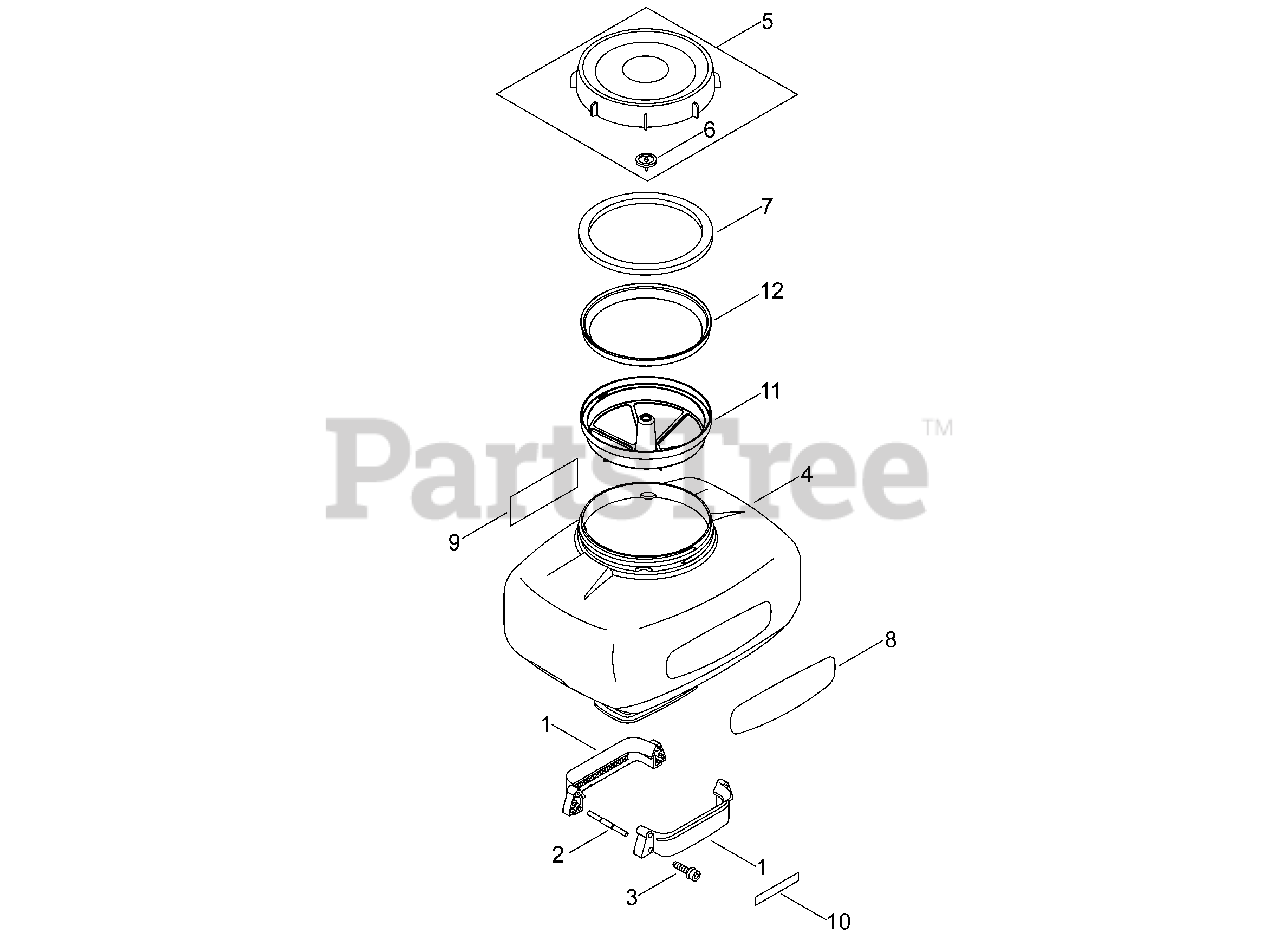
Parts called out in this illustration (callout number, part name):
1	BRACKET
2	PIN, LOCATING
3	SCREW, TAPPING HS M5×35
4	TANK, CHEMICAL 23L
5	CAP ASSY, CHEMICAL TANK
6	CONNECTOR, PIPE
7	GASKET, CAP
8	LABEL, ECHO
9	LABEL, CAUTION - ISO
10	LABEL, MODEL DM-6120
11	FILTER, TANK
12	FILTER, TANK
